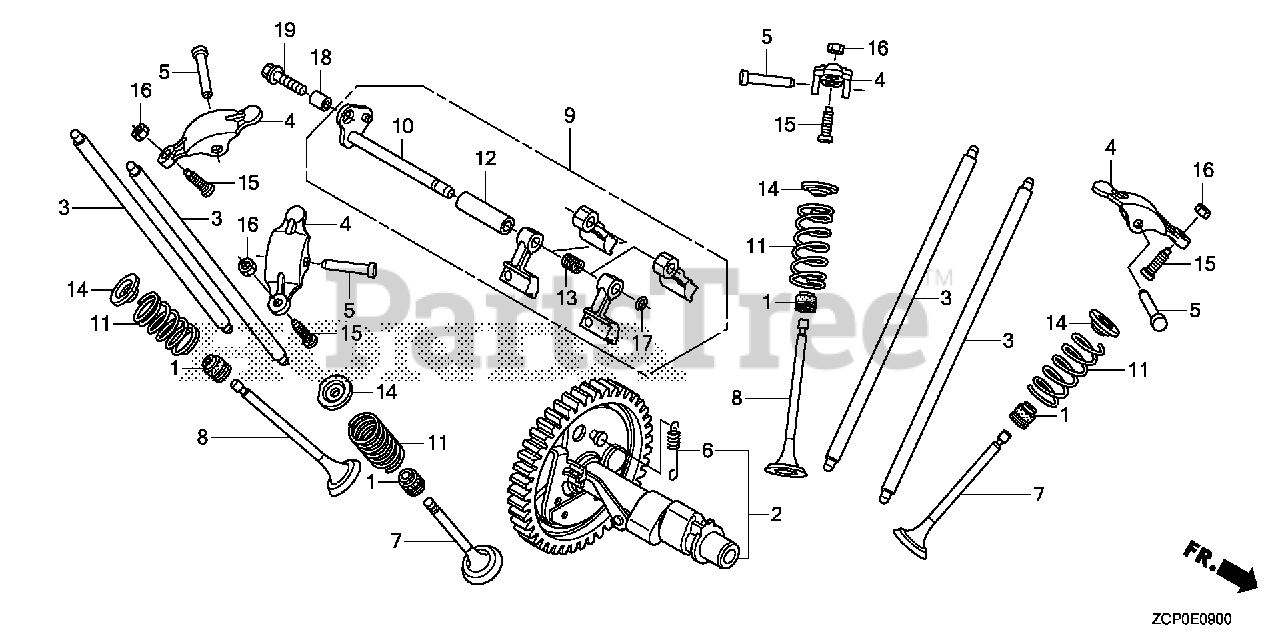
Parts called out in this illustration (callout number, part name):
1	SEAL, VALVE STEM
2	CAMSHAFT ASSY.
4	ARM, VALVE ROCKER
5	SHAFT, ROCKER ARM
6	SPRING, WEIGHT RETURN
7	VALVE, IN.
8	VALVE, EX.
9	LIFTER ASSY., VALVE
10	SHAFT, VALVE LIFTER
11	SPRING, VALVE
12	COLLAR, VALVE LIFTER
13	SPRING, VALVE LIFTER
14	RETAINER, IN. VALVE SPRING (IN./EX.)
14	RETAINER, VALVE SPRING
15	SCREW, TAPPET ADJUSTING
16	NUT, TAPPET ADJUSTING
17	CLIP, GOVERNOR HOLDER
18	PIN, DOWEL (8X10)
19	BOLT, FLANGE (6X22)
